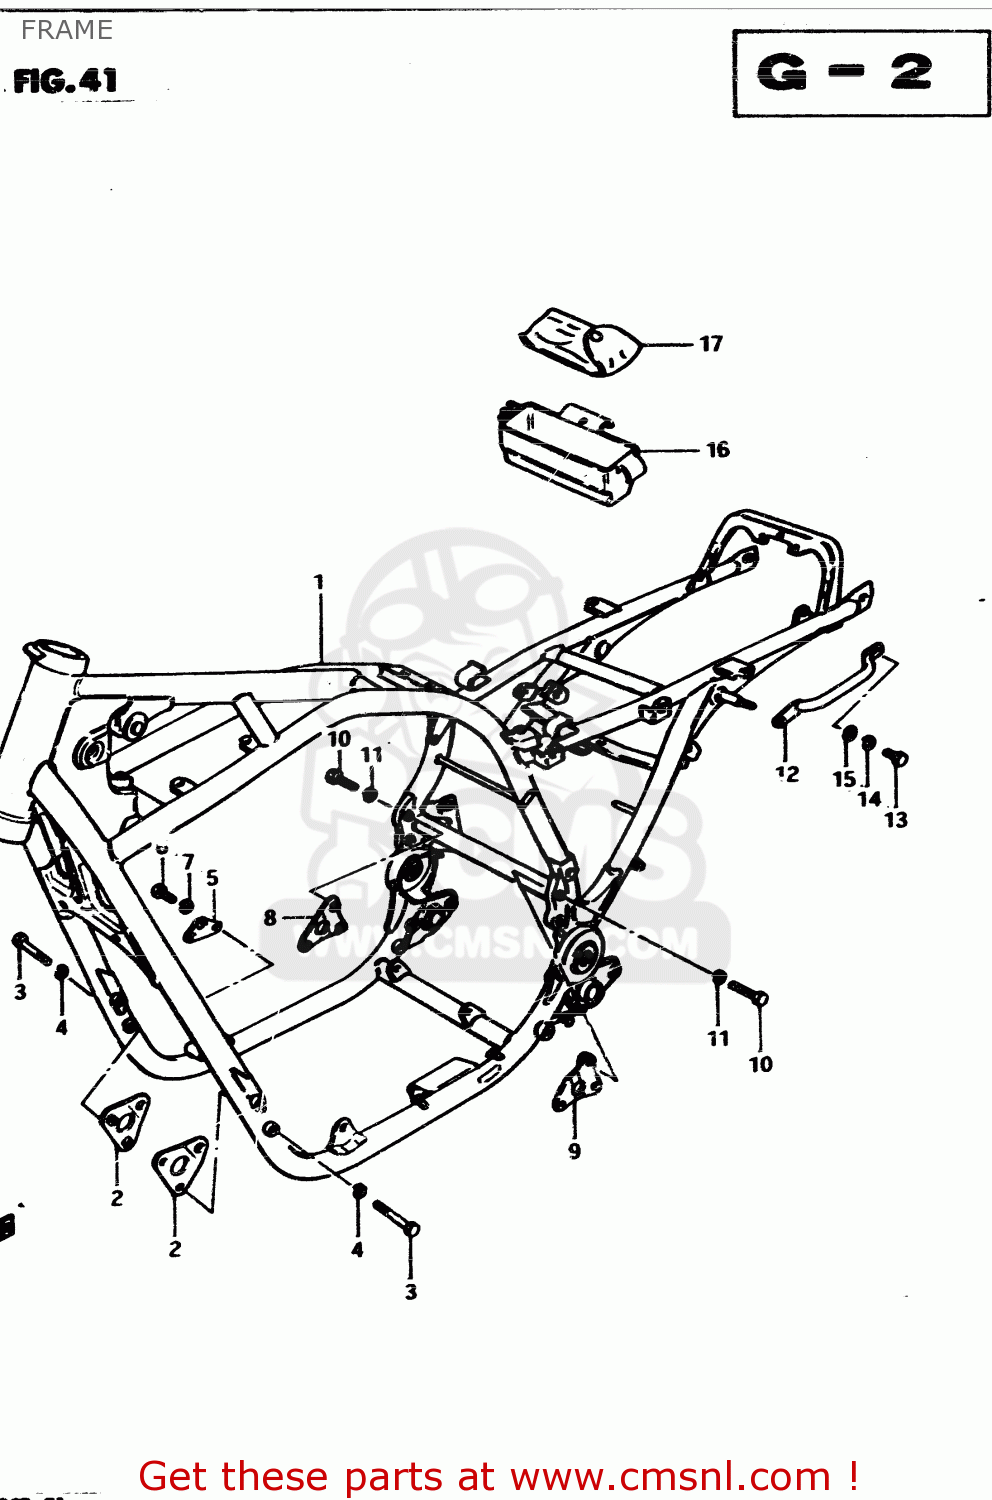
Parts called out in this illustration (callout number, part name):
1	FRAME
2	PLATE,ENGINE MOUNTING
3	BOLT
4	LOCK WASHER
5	PLATE,ENGINE MOUNTING
6	BOLT
7	LOCK WASHER
8	PLATE,ENGINE MOUNTING
9	PLATE,ENGINE MOUNTING
10	BOLT 8X40
11	LOCK WASHER
12	GRIP,FRAME HANDLE
13	BOLT
14	LOCK WASHER
15	WASHER
16	HOLDER,TOOL
17	TOOL SET
